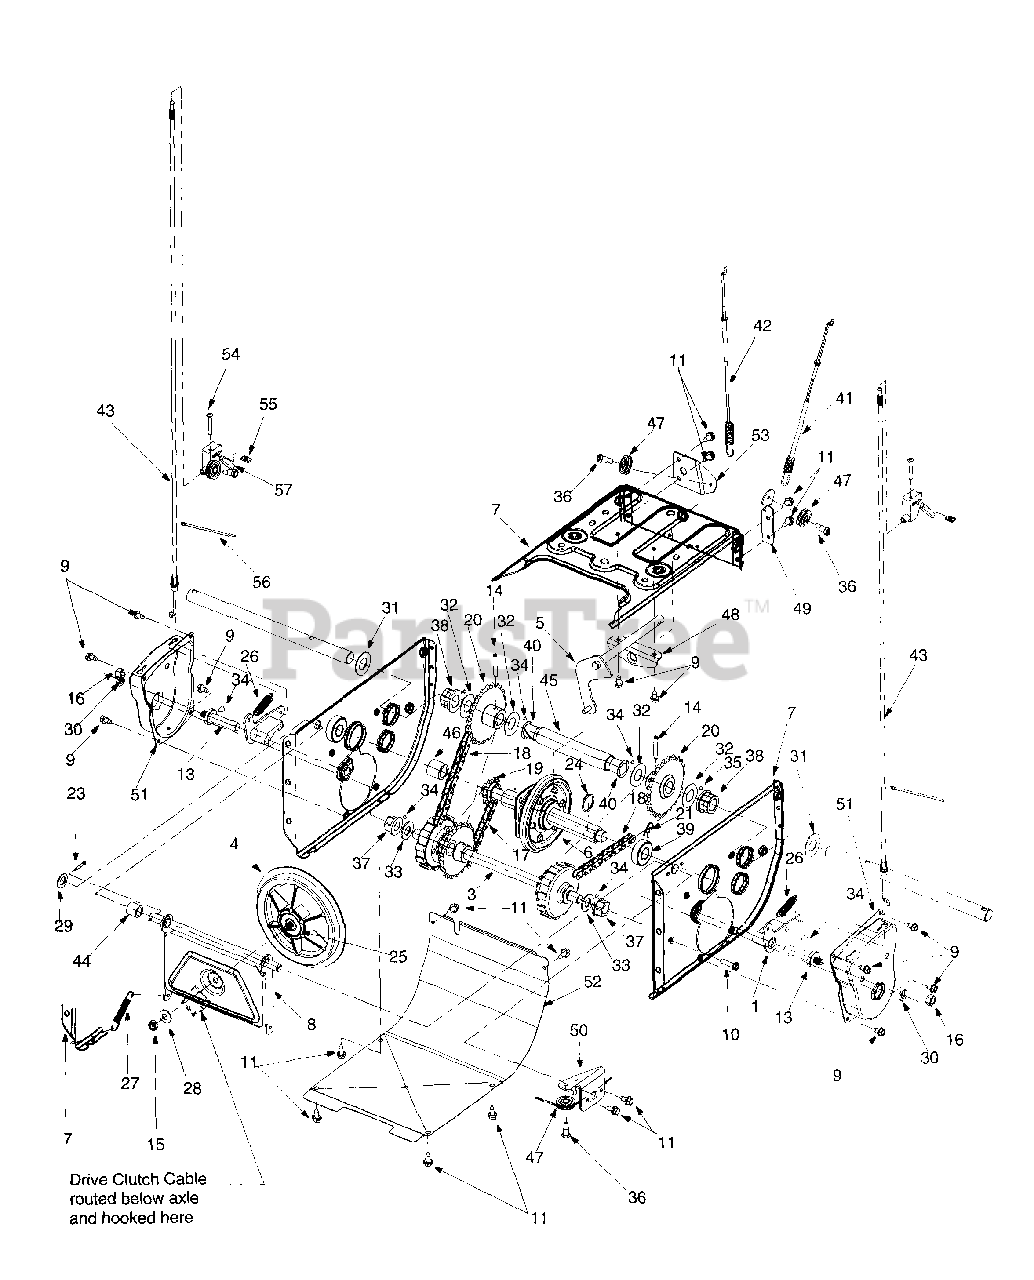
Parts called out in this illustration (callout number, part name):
1	Dogg Assembly: RH
2	Dogg Assembly: LH
3	Shift Assembly: Steerable Drive
4	Friction Wheel Disc Assy.
5	Shift Rod Assembly
6	Wheel Assembly, Friction
9	Hex Washer Hd. TT Screw 1/4-20 x 0.5"
10	Hex Washer Hd. TT Screw 1/4-20 x 1.0"
11	Hex Washer Hd. TT Screw 1/4-20 x .625"
12	Drive Shaft
13	Actuator Shaft
14	Clevis Pin
15	Jam Nut 3/8-24 Gr.8
16	Hex Nut: 3/8-16
17	Chain
18	Chain
19	Sprocket: 10T
20	Sprocket
21	Cotter Pin
23	Cotter Pin
24	Snap Ring
25	Adhesive: Loctite(R)
26	Extension Spring
27	Extension Spring
28	Bell Washer
29	Flat Washer
30	Lock Washer
31	Flat Washer
32	Flat Washer
33	Flat Washer
34	Lubricant
35	Grease
36	Shoulder Screw
37	Hex Flange Bearing
38	Hex Flange Bearing
39	Ball Bearing
40	Flange Bushing
41	Auger Clutch Cable
42	Drive Clutch Cable
43	Steering Cable
44	Spacer
45	Support Tube: Axle
46	Spacer
47	Roller Cable
49	Auger Clutch Cable Guide Bracket
50	Front Support Guide Bracket
51	Retaining Shaft: Actuator Drive
54	Oval C-Sunk Machine Screw
55	Weld Nut
56	Cable Tie
57	Turn Trigger
